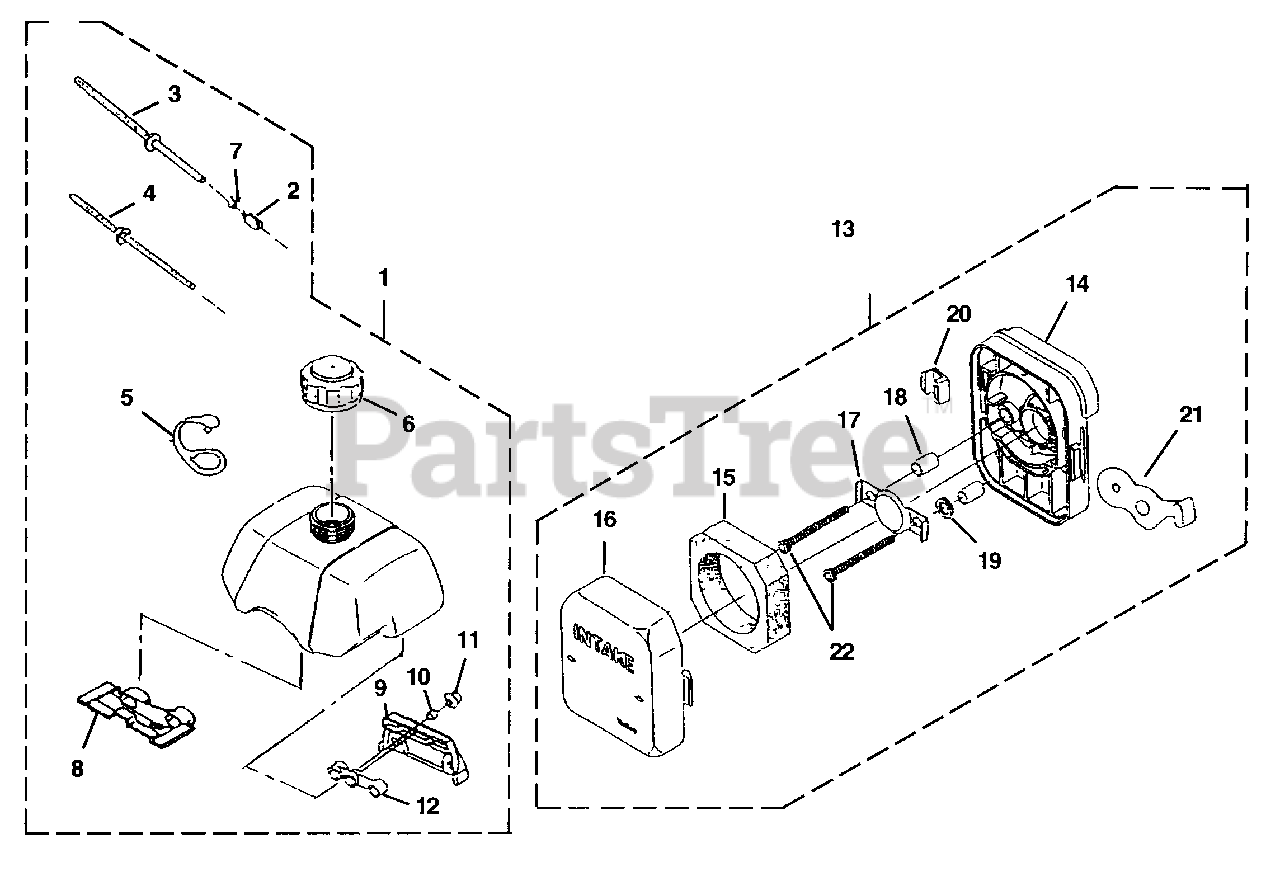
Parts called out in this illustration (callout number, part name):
1	FUEL TANK ASSEMBLY
2	FILTER-Fuel
5	CAP- Retainer
6	CAP - Fuel
7	HOSE CLAMP
8	BUMPER, Fuel Tank
9	BRACKET - Fuel Tank
11	BOLT (M5 X 14W)
12	BUMPER-Fuel Tank
13	AIR FILTER ASSEMBLY
14	BODY-Air Filter
15	FILTER-Air
16	COVER-Air Filter
17	PLATE-Air Filter
20	CLIP-Filter Cover
21	VALVE, CHOKE
22	SCREW-Socket Hd (M5 X 50)
